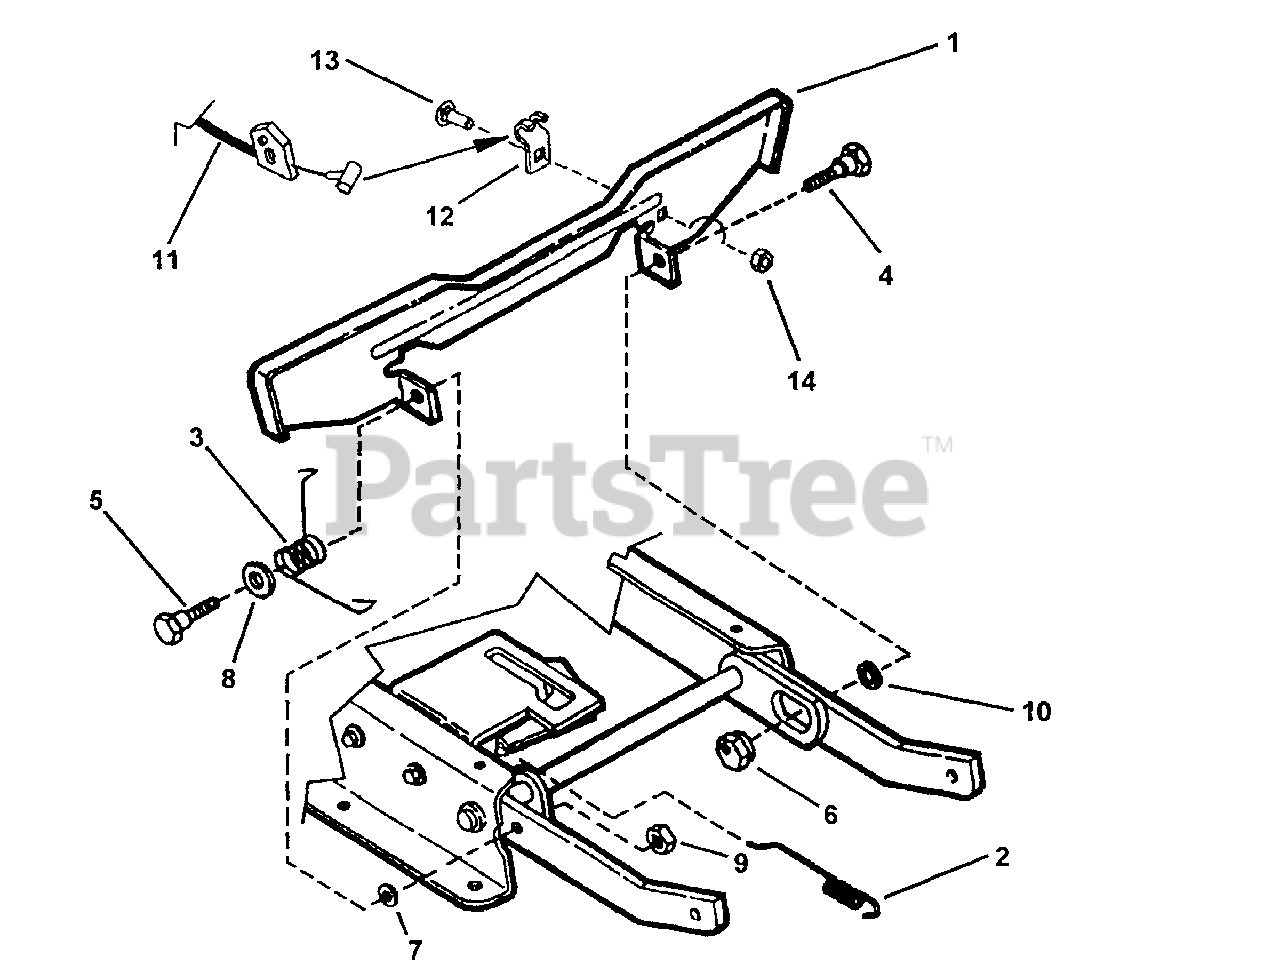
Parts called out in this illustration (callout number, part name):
1	PEDAL, Blade Stop Control
2	SPRING, Latching
3	SPRING, Pedal
4	BOLT, 3/8-24 x 3/4" Shoulder
5	BOLT, 3/8-24 x 9/16" Shoulder
6	ECCENTRIC, Leveling
7	WASHER, 3/8" Flat
8	WASHER, 1/2" Flat
9	NUT, 3/8-24 Hex Center Lock
10	WASHER, 3/8" Internal Tooth Lock
11	CABLE, No Reverse In Mow
12	CLIP, Cable
13	BOLT, 1/4-20 x 3/4" Square Neck Carriage, Grade 5
14	NUT, 1/4-20 Hex, Grade 5 or B
